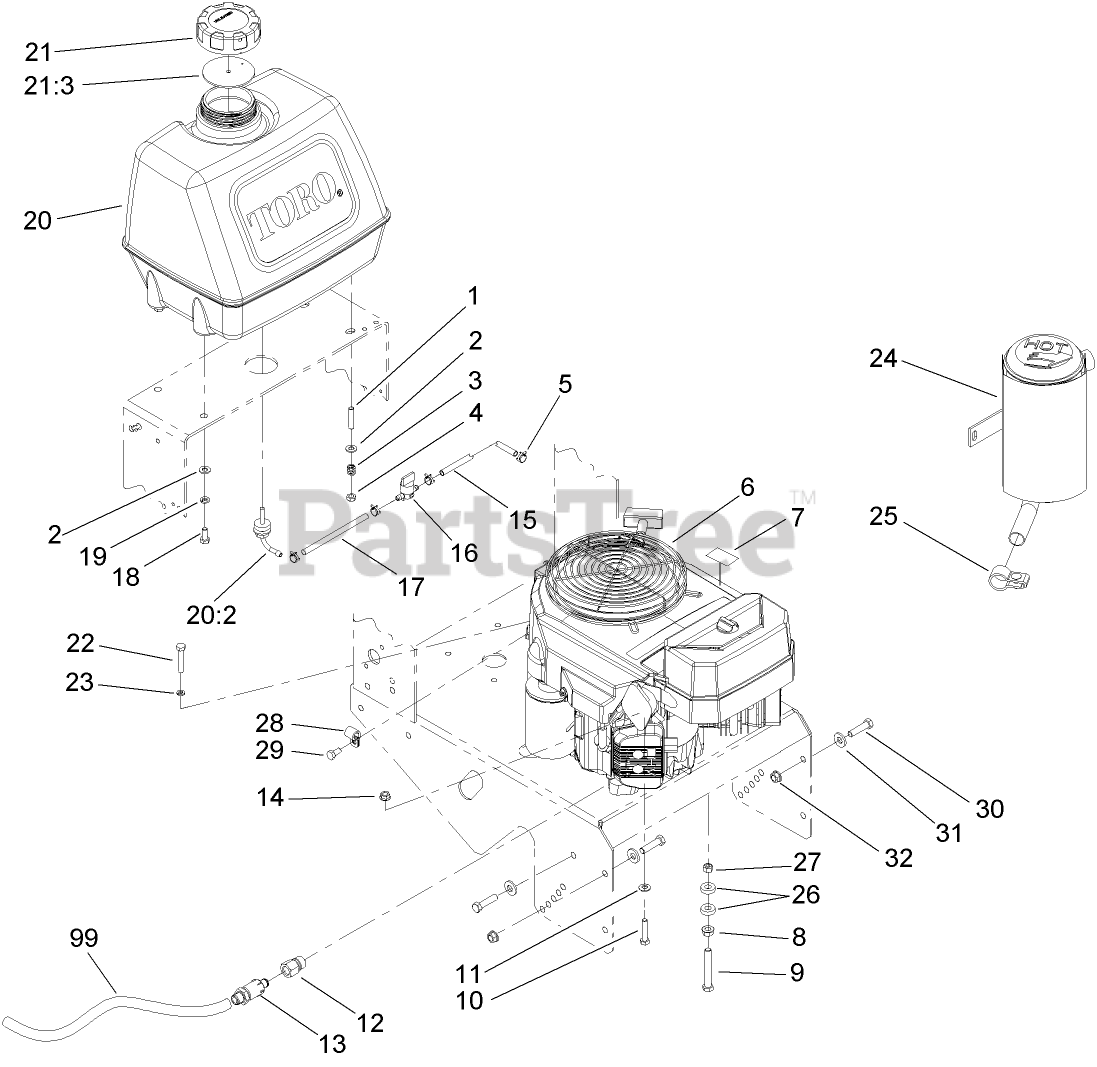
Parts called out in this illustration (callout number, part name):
2	WASHER-PLAIN
3	SPRING-TANK, FUEL
4	NUT-LOCK, NI
7	DECAL-WARNING
8	NUT-HF
9	SCREW-HH
10	SCREW-HH
11	WASHER-SPRING
12	Adapter
13	VALVE-DRAIN, OIL
14	NUT-HF
15	HOSE-FUEL
16	VALVE-FUEL
17	HOSE-FUEL
18	SCREW-HH
19	WASHER-LOCK
20	FUEL TANK ASM
20:2	FITTING-FUEL, BULKHEAD
21	GAS CAP ASM
21:3	GASKET-CAP, GAS
22	SCREW-HH
23	WASHER-LOCK
24	MUFFLER
25	CLAMP-MUFFLER
26	SPACER
27	NUT-LOCK, NI
28	Clip-Loom
29	SCREW-HH
30	SCREW-HH
31	WASHER-BELLEVILLE
32	NUT-HHF, WHIZ
99	HOSE-DRAIN, OIL
